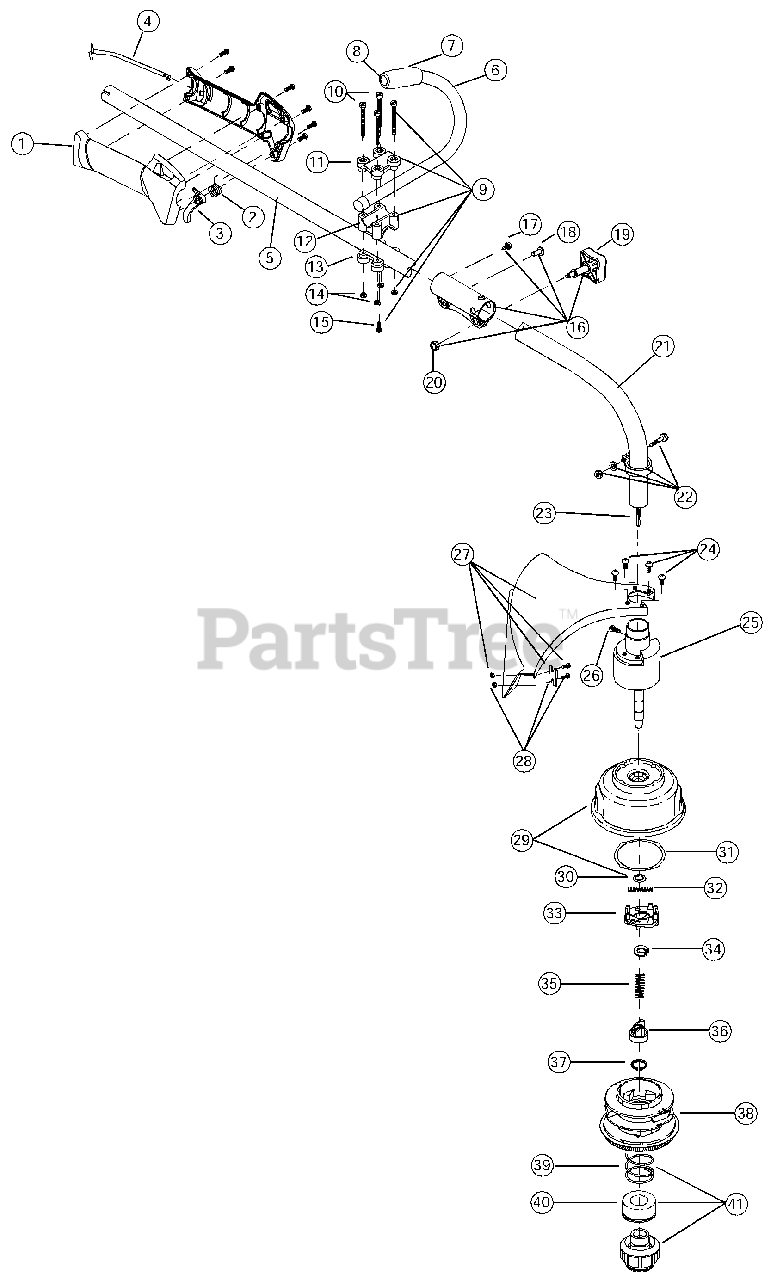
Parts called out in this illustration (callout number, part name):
1	Throttle Housing & Trigger Assembly
2	Throttle Trigger Spring
3	Throttle Trigger
4	Throttle Cable Assembly
5	Upper Drive Shaft Housing Assembly
6	J-Handle Assembly
8	Tube Closure
9	Handle Bracket Assembly
11	Upper Handle Clamp
12	Middle Handle Clamp
13	Lower Handle Clamp
15	Anti-Rotation Screw
16	Click-Link Coupler
19	Adjustment Knob
20	Knob Retaining Nut
21	Lower Drive Shaft Housing Assembly
22	Lower Clamp Assembly
23	Lower Flexible Drive Shaft
24	Shield Mounting Screw
25	Bushing Housing Assembly
26	Anti-Rotation Screw
27	Shield and Blade Assembly
28	Blade Assembly
29	Outer Spool and Eyelet Assembly w/ Retainer
30	Retainer
31	Thrust Washer
32	Small Spring
33	Slider
36	Plunger
38	Inner Reel
39	Large Spring
40	Foam Seal
41	Bump Head Knob Assembly w/Spring & Foam Seal
